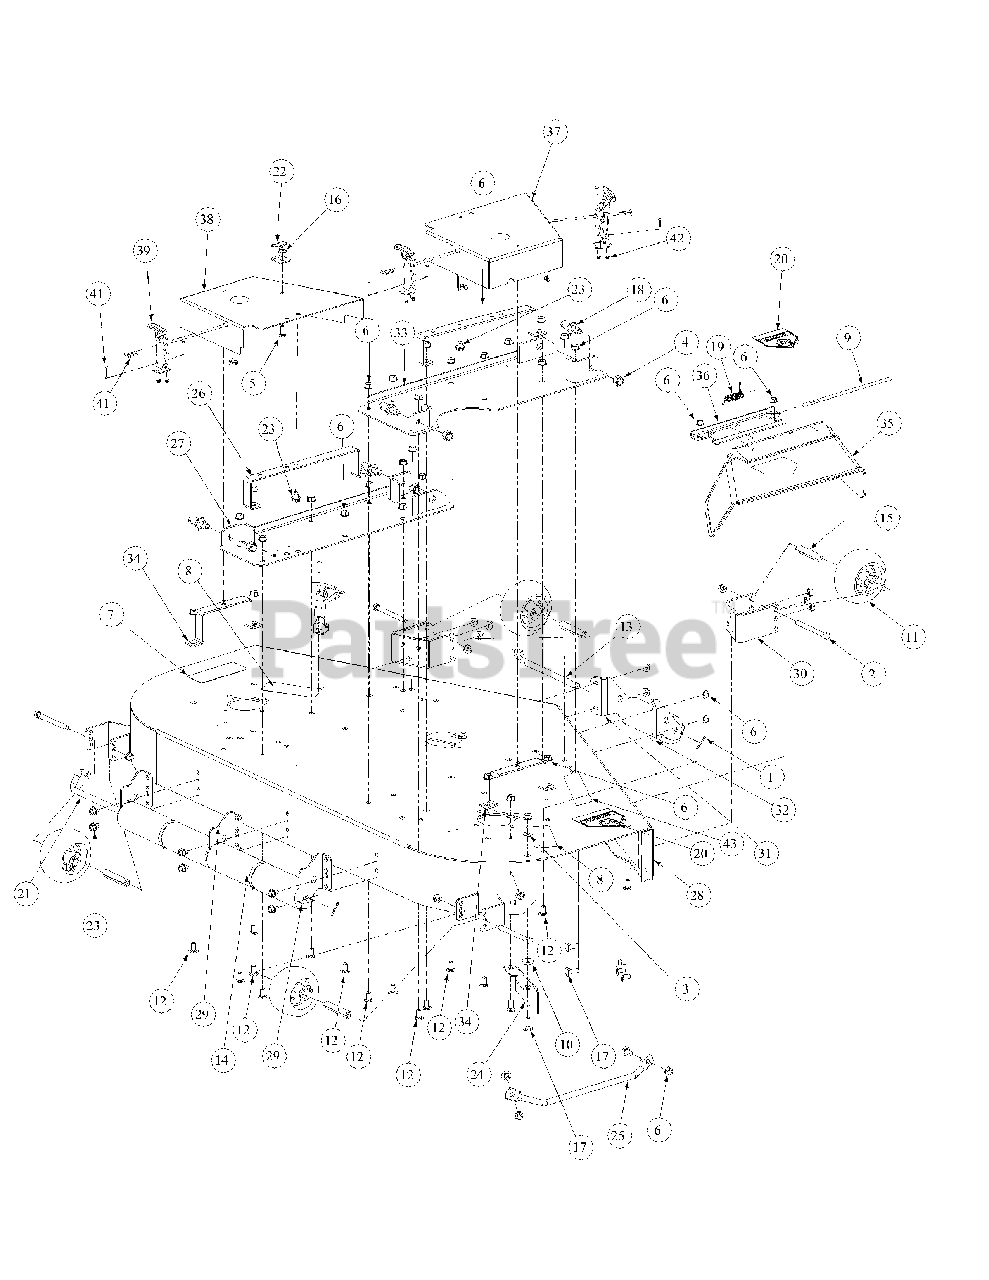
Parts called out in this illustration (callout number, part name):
1	Cotter Pin, .125 Dia x 1.0
2	Hex Cap Screw, 3/8-16, 3.75
3	Flat Washer, 3/8
4	Lock Nut, Nylon Insert, 1/2-13
5	Hex Cap Screw, 5/16-18 x 3/4
6	Hex Nut, 3/8-16 Flange Lock
7	Decal Rotating Blade
8	Decal, Warning Shield Missing
9	Deflector Chute Rod
10	Idler Washer
11	Complete Wheel, 5.00 Dia.
12	Carriage Bolt, 3/8-16 x .75 Lg.
13	Roller Pin. 1/2 Dia. x 7.31 Lg.
14	Front Roller
15	Wheel Spacer
16	Hexflange Lock Nut, 5/16-18
17	Carriage Bolt, 3/8-16 x 1
18	Pin, 5/8 Dia. x 1.2 Lg.
19	Spring Torsion, 0.4 ID x 2.16 LG
20	Decal, Danger Hands and Feet
21	Roller Pin
22	Tension Rod Stop Bracket
23	Hex Index Washer Screw, 3/8-16, .5
24	Chute Bracket
25	Finger Guard
26	Cover Support
27	Left Hand Mount, Deck Bracket Assembly
28	54 Deck Assembly
29	Roller Mount Bracket
30	Anti-Scalp Wheel, Front Mount Bracket
33	Deck Bracket Assembly
34	Outer Belt Cover Support Assembly
35	Deflector Chute
36	Deflector Chute Bracket
37	Right Hand Belt Deck Cover Weldment
38	Left Hand Belt Deck Cover Weldment
39	T-Handle Draw Latch
41	Phillips Head Screw, 10-32
42	Lock Nut, Nylon Insert, 10-32
43	Mower Deck Label
